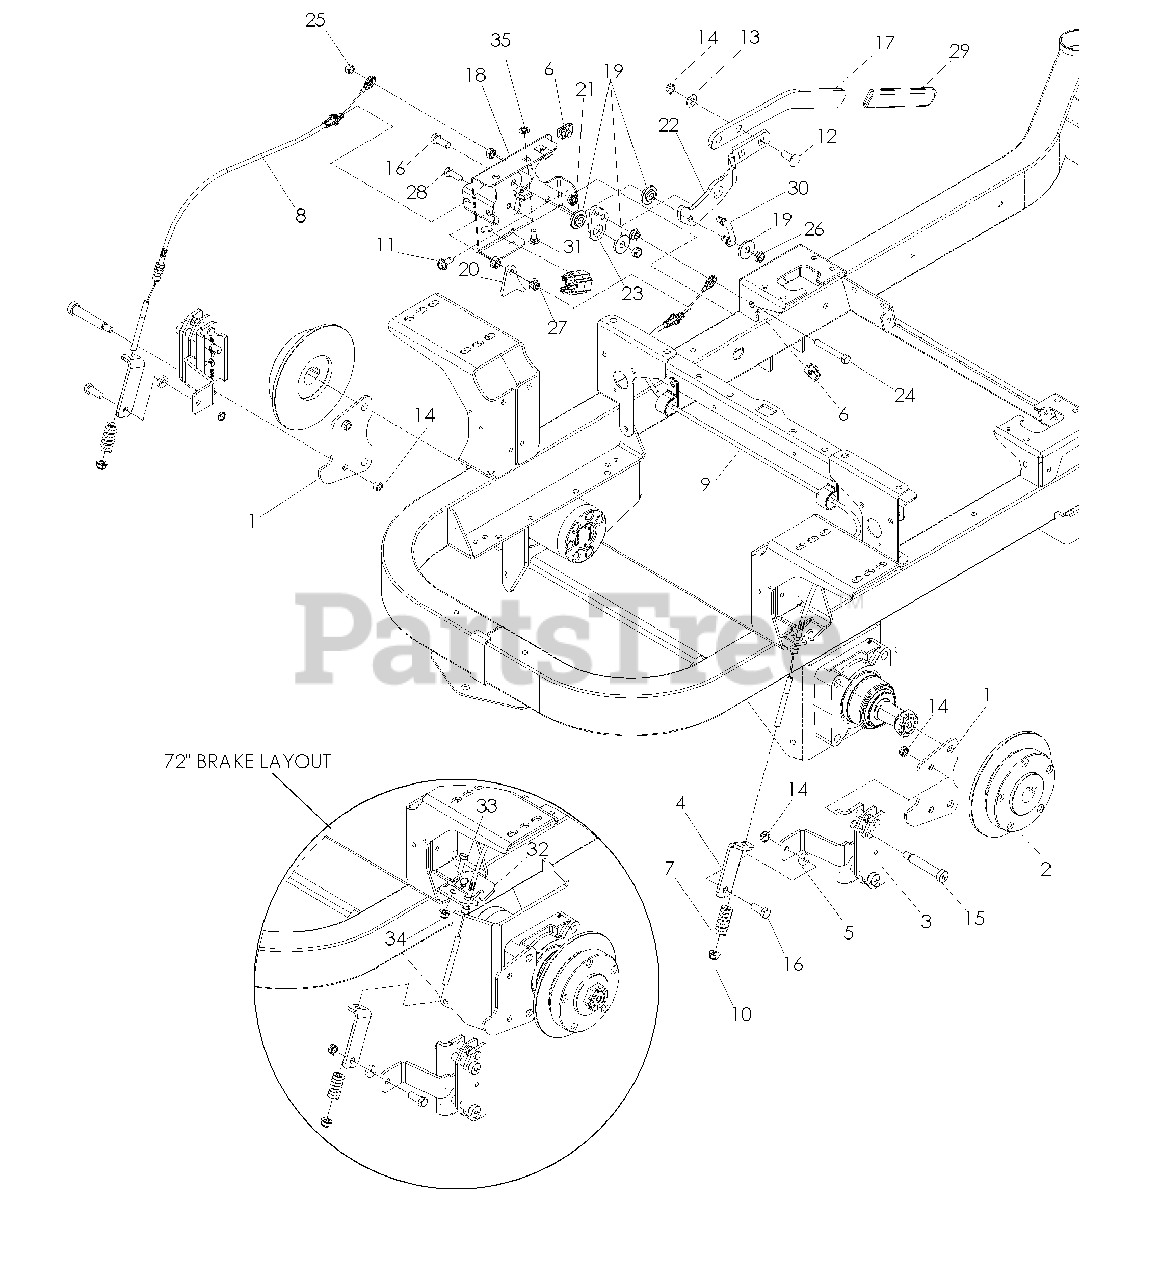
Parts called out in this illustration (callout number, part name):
1	PLATE, BRAKE
2	HUB, 5 BOLT
3	CALIPER PARK BRAKE
4	BRACKET, L
5	WASHER 3/8 X 3/4 X .187 TK
6	U-CLIP 5/16-18 NUT RETAINER
8	CABLE, BRAKE, SHORT
9	CABLE, BRAKE, LONG
10	5/16-18 NYLOC FLANGE NUT
11	BOLT 5/16-18 X 3/4
12	RHSNB 3/8C X 1
13	WASHER 3/8 SAE FLAT
14	NUT HEX 3/8-16 NYLON, THIN
15	SB 3/8-16 X 2-1-1/2 SKT HDD ZD
16	HCS 3/8C X 1
17	ARM, BRAKE, BLK
18	MOUNT, BRAKE WLDMT
19	BUSHING, BRAKE
20	ACTUATOR, SWITCH
21	NUT 5/16C WHIZ
22	LEVER, BRAKE
23	BELLCRANK, BRAKE
24	HCS 5/16-18 X 2 1/2 TPBLT
25	NUT 5/16 NYLOC
26	NUT HEX 3/8-16 NYLON, THIN
27	5/16-18 NYLOC FLANGE NUT
28	HCS 5/16C X 1
29	GRIP BRAKE HANDLE
30	LINKAGE, BRAKE
31	BOLT 5/16C X 3/4" CARRIAGE
32	BRKT, EXTENSION
33	HCS 5/16C X 1
34	5/16-18 NYLOC FLANGE NUT
